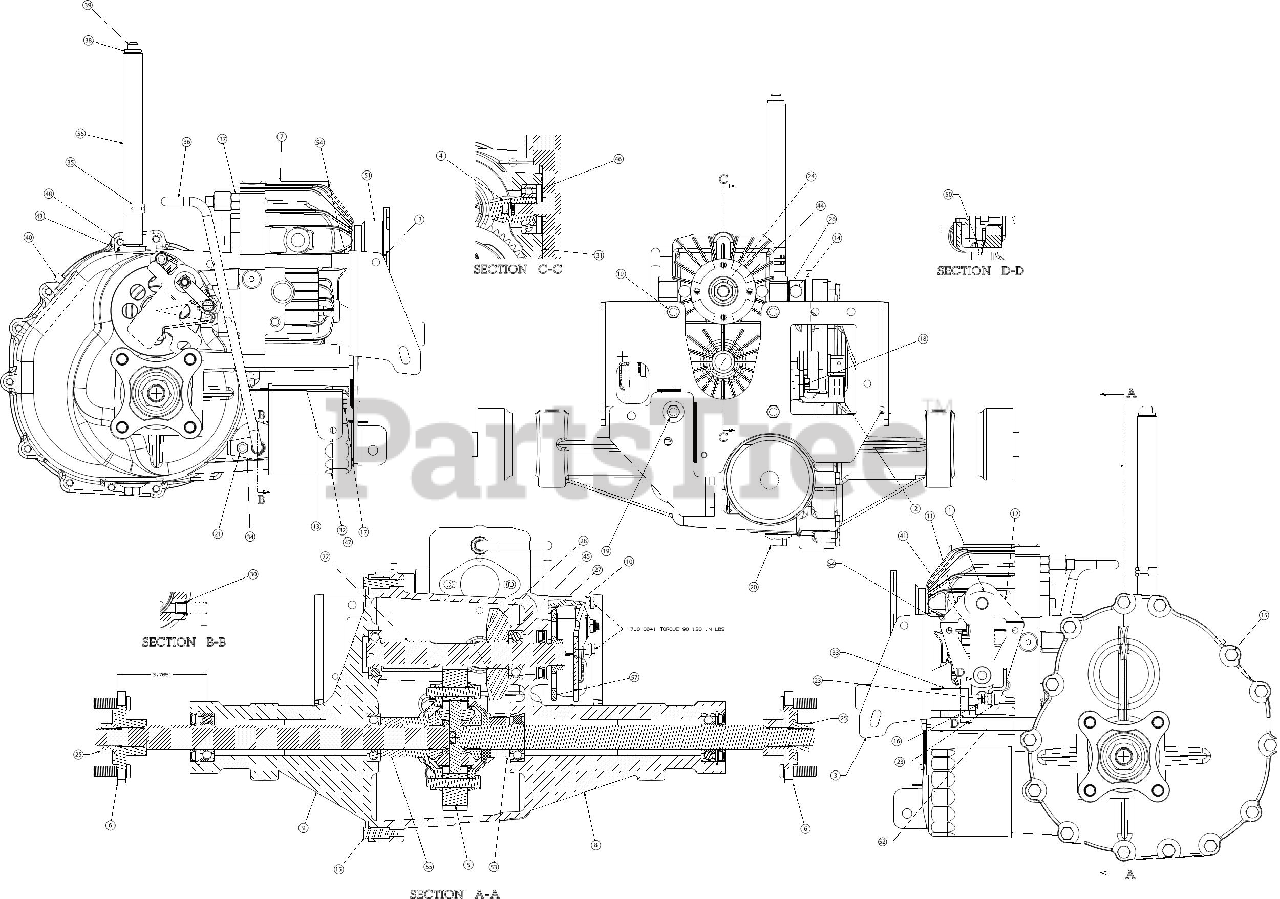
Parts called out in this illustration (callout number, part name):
1	NEUTRAL CONTROL ARM
2	NEUTRAL RETURN ARM
3	TORQUE BRACKET ASSEMBLY
4	13T PINION GEAR ASSEMBLY
6	WHEEL HUB ASSEMBLY
7	HYDROPUMP ASSEMBLY
8	TRANSMISSION HOUSING (RH)
9	TRANSMISSION HOUSING (LH)
10	BRAKE PUCK
11	NEUTRAL ARM (LH)
12	NEUTRAL ARM (RH)
13	DUMP VALVE PLATE
14	BOLT 5/16-24 x .625 GR2
15	SCREW 5/16-18 x 1.25 GR5
16	SCREW 1/4-20 X1.00 GR5
17	SCREW 1/4-20 X.500
18	SCREW 5/16-18 x .500
19	SCREW 5/16-18 x 5.19 GR5
20	SCREW M14X1.5X.827
21	SCREW 1/4-20X.75 GR5
22	OUTPUT SHAFT 9T
25	HEX FLANGE NUT 3/4
26	SNAP RING FOR .875 SHAFT
27	BRAKE PUCK
28	BEVEL GEAR 54T
30	O-RING .426X.566X.070
31	GLAND SEAL
32	HYDRAULIC FILTER
33	INTERLOCK SWITCH (NO/NC)
34	TUBE CLAMP
35	FUEL HOSE CLAMP
36	HYDRO PICKUP TUBE
37	SWIVEL CONNECTOR
38	PLASTIC VENT
40	SHIPPING ONLY
41	EXTENSION SPRING
43	VENT FITTING GROMMET
44	BELL WASHER
45	THRUST WASHER
46	SPRING WASHER
47	NIPPLE-OIL FILTE
48	VENT TUBE FITTING
50	SHOULDER SCREW
51	PUMP ADAPTER SPLINED
52	HYDRO SPACER .364 x .540 x 3.51
53	AXLE SPACER 1.0X1.
54	SPACER-HYDRO .323X.600 x .740
55	AXLE SPACER 1.0X1.665 x .989
56	FUEL LINE 1/2" ID
57	BRAKE-DISC 43TEETH
